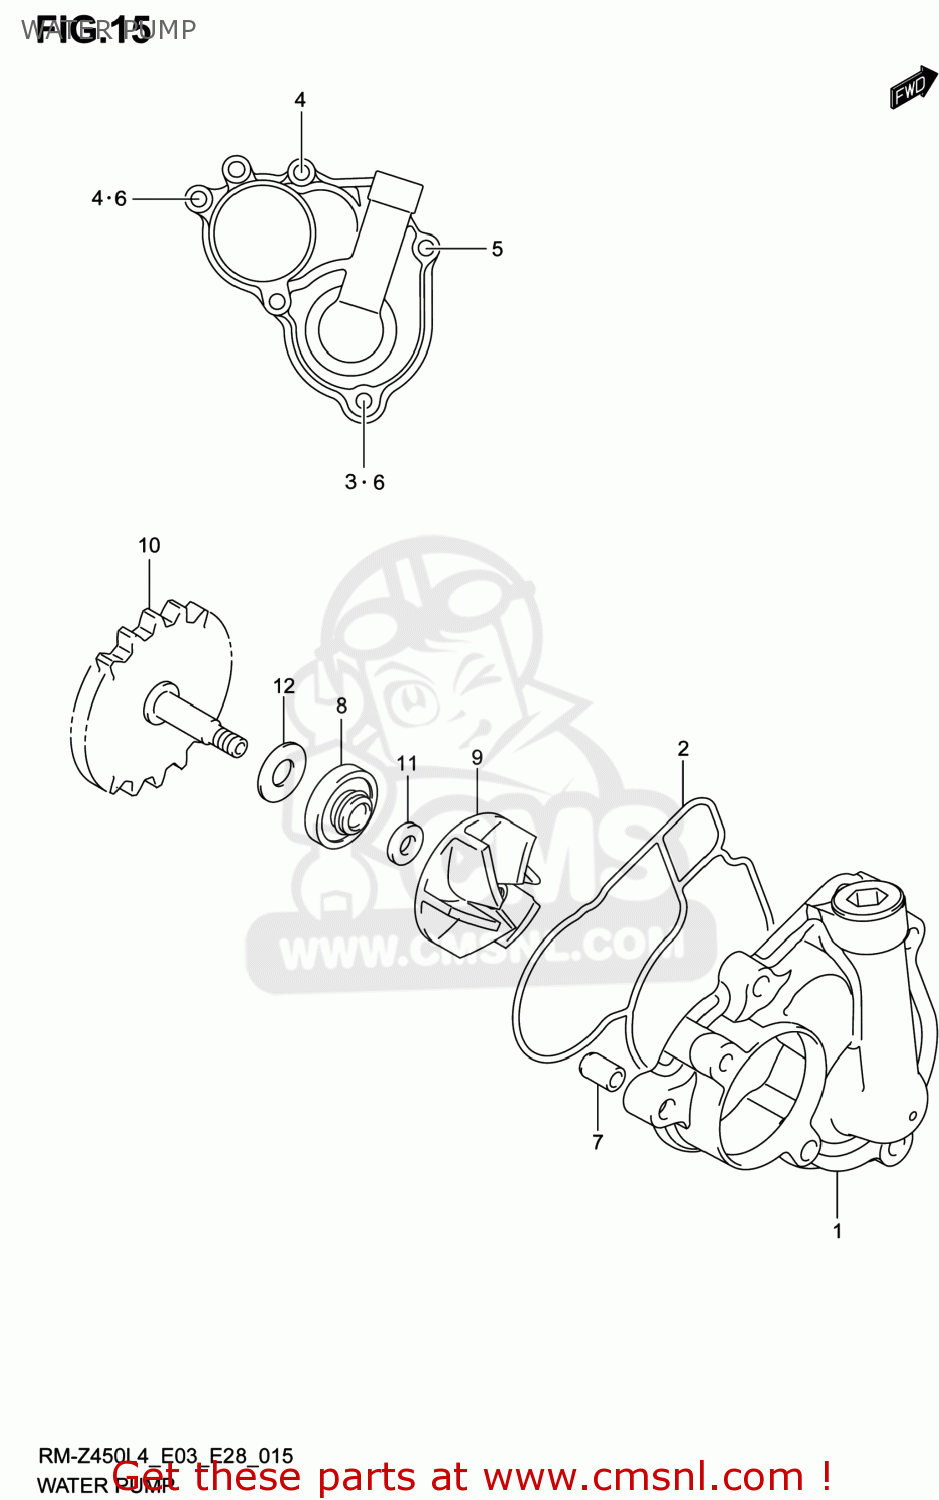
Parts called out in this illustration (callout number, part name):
1	CASE,WATER PUMP
2	O RING,WATER PUMP CASE
3	BOLT
4	BOLT
5	BOLT
6	GASKET(5.8X13X1.2) (NAS)
7	PIN(6.2X8X11)
8	SEAL,WATER PUMP OIL
9	IMPELLER,WATER PUMP
10	SHAFT,WATER PUMP
11	SHIM(6X14X1)
12	SHIM(8X18X0.5)
